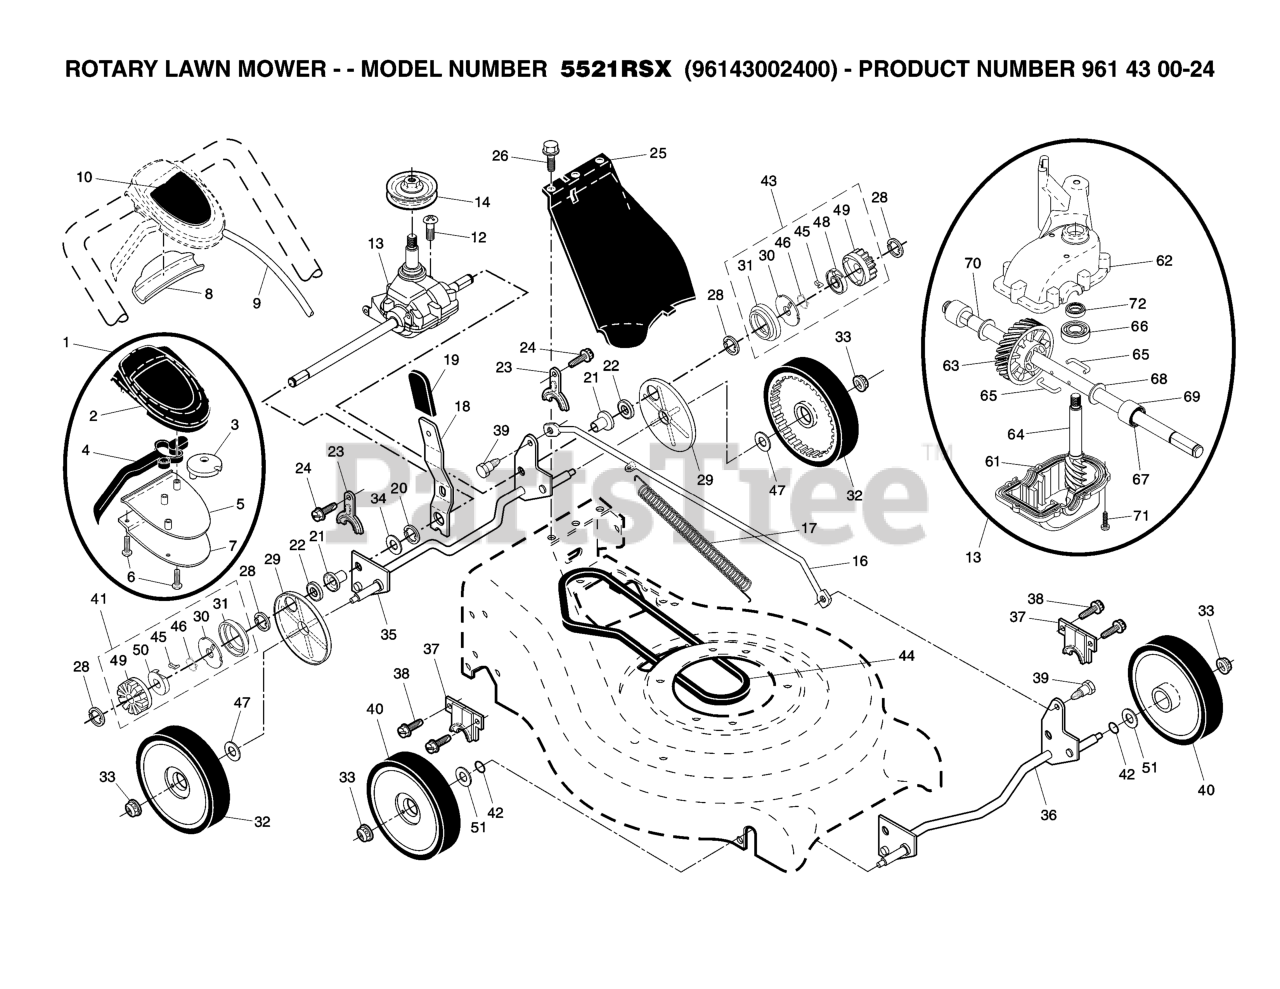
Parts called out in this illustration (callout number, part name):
1	CONTROL.DR.AW.GRY.RWGD.BLACK
2	CASE.TOP.GRAY
3	PULLEY.CAM.DRIVE.CONTROL.HV
4	LEVER, AUTOWALK DRIVE CONTROL
5	CASE BOTTOM
6	SCREW, PHILLIPS HEAD 10 X 5/8
7	BRACKET.DRIVE.CONTROL.MOUNT.BL
8	EZ WALK SNAP COVER PLATE
9	DRIVE CONTROL CABLE
10	DECAL, DRIVE
13	TRANSMISSION.21.RWGD.EZ/AW/VS
14	PULLEY.1.PIECE
16	ROD.CONNECTING.SPT.BLACK
17	SPRING
18	SPRING.SELECTOR.SPT.21
19	KNOB, SELECTOR SPRING
21	RP BEARING SUPPORT
22	BEARING, BALL
23	BRACKET
25	COVER.DRIVE.21.RWGD.MO
28	E-RING 7/16 RE
29	COVER.DUST.WHEEL
30	DISC.DRIVE.21.EZ-WALK
31	SEAL.PINION
32	WHEEL.8X1.75.H3SPK.RAD3.GY.BU3
33	HEX FLANGE LOCKNT
35	SHAFT ASSY REAR
36	SHAFT ASSY, FRONT
37	RETAINER.FRONT.SHAFT
39	SHOULDER BOLT SEMI GIMLET PT.
40	WHEEL & TIRES ASSY, FRONT
41	PINION ASSY, RH
42	O-RING..070X.487.NEOPRENE
43	PINION ASSY, LH
44	BELT.DRIVE.EZ.WALK.HI-VAC
45	PAWL.DRIVE.21.EZ-WALK
46	SPRING, TORSION
47	WASHER FLUT
48	RETAINER.DRIVE.21.EZ-WALK.LT
49	GEAR, PINION
50	RETAINER, DRIVE, RH
51	WASHER.FLAT.1/2
61	CASE, LOWER
62	CASE, UPPER
63	GEAR.24.TOOTH.WALK.MOWER
64	SHAFT INPUT
65	WIRE, FORMED (15966)
67	SEAL.OUTPUT.SHAFT
70	RP.SHAFT.OUTPUT.RGD.VS/EZ
72	SEAL INPUT SHAFT
